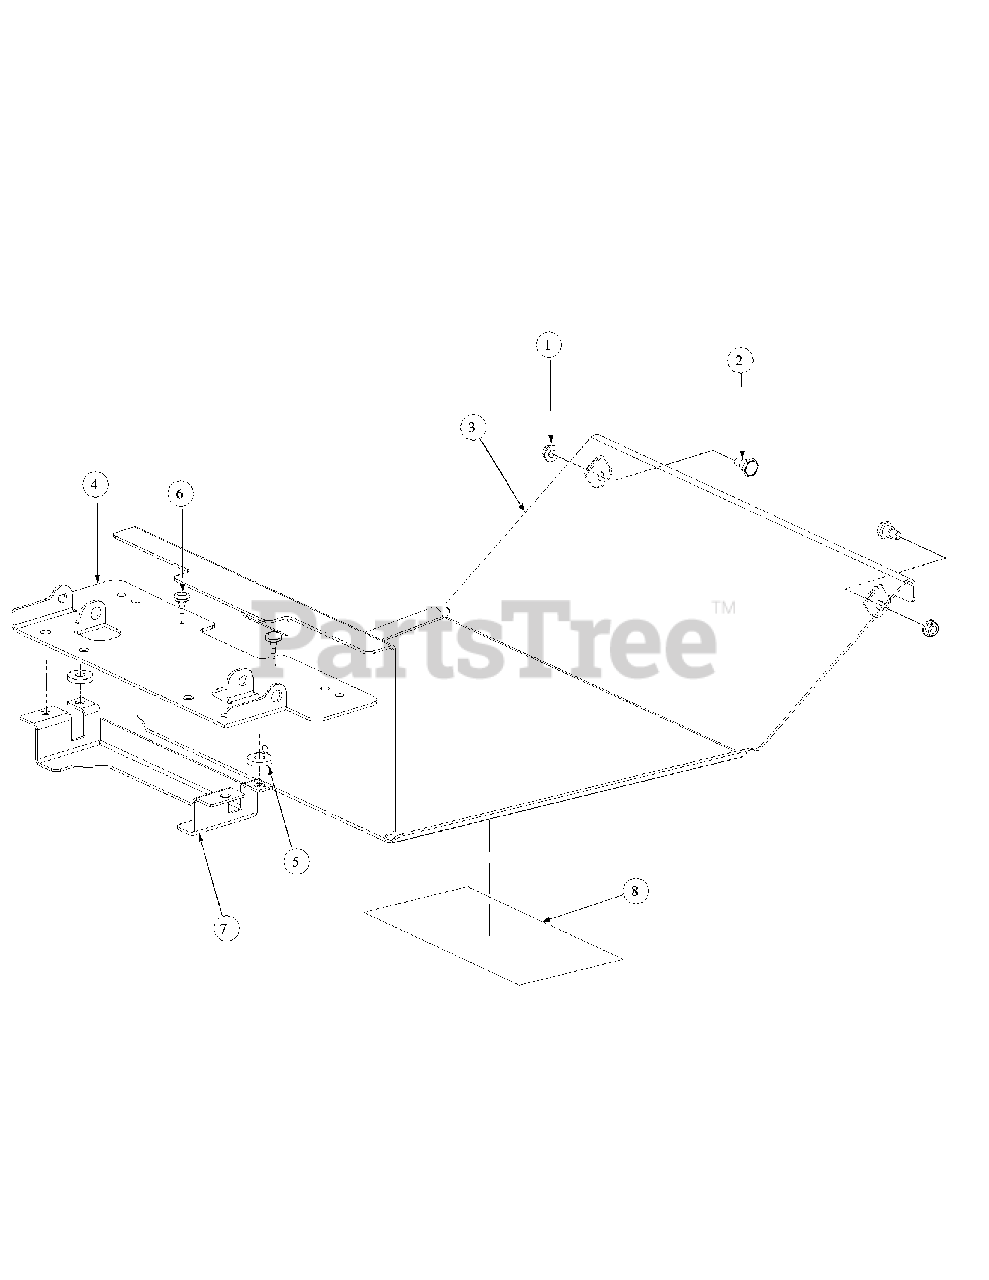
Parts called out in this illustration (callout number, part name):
1	Lock Nut, Hex Flange 5/16-18
2	Shoulder Screw, .435 x .350, 5/16-18
3	Floor Assembly Panel
5	Washer
6	Rubber Bumper, .62 OD x .22 Thick
7	Support, Seat Bracket
8	Label, Belt Routing and Lubrication
